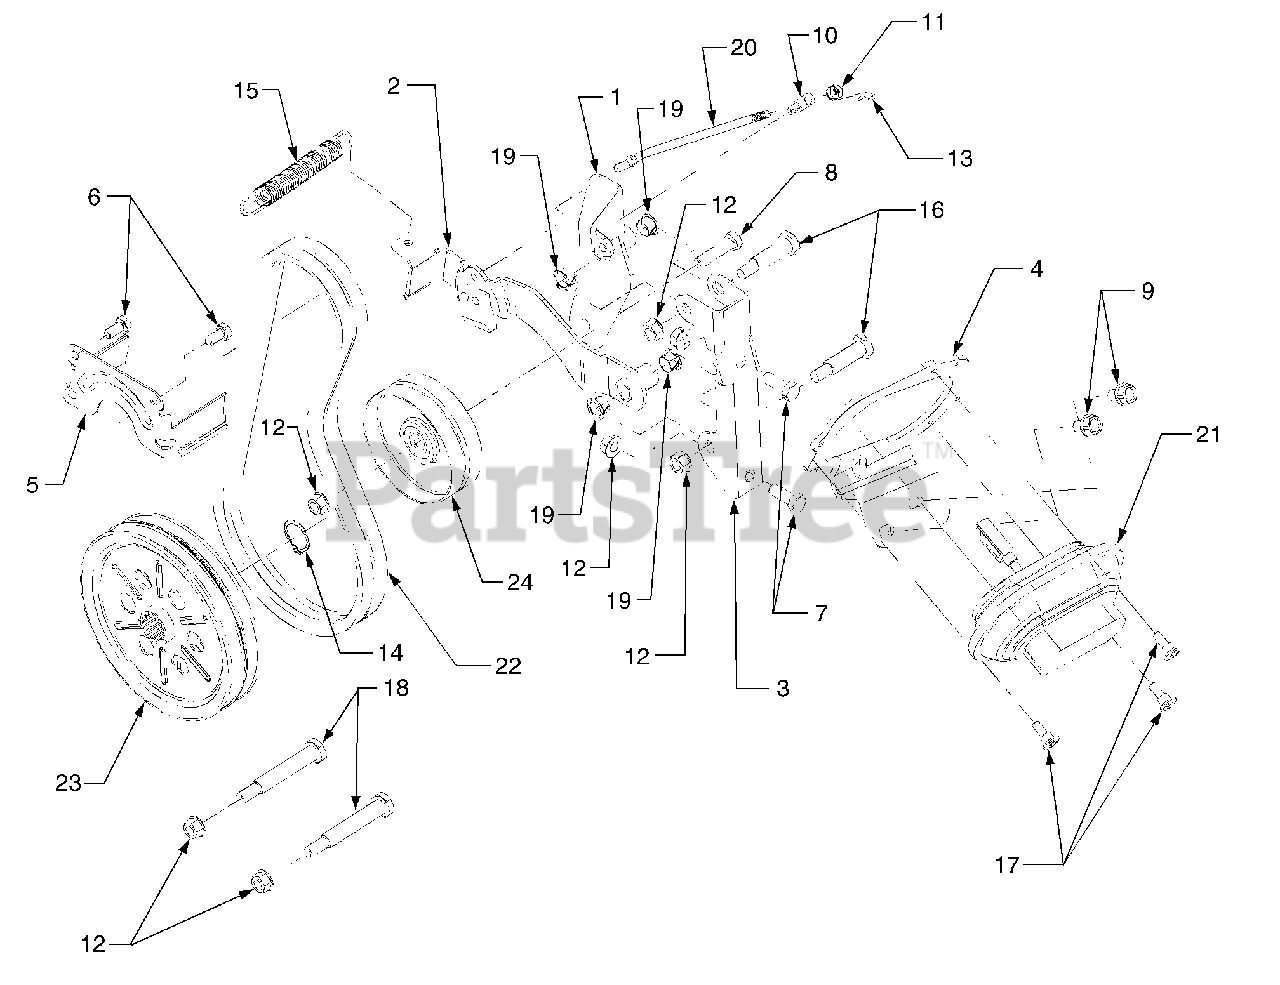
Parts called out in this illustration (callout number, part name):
1	Bracket, Idler
2	Bracket Assembly, Brake
3	Bracket, PTO Mounting
4	Bracket, Actuator
6	Screw, Hex Cap 5/16-24 x .625 GR5
7	Screw, Hex Cap 3/8-16 x 1.0 GR5
8	Screw, Hex Cap 3/8-16 x 1.5 GR5
9	Screw, Hex Wash. Hd. Tapp 3/8-16 x .75
10	Ferrule, Brake Adjustment
11	Nut, Hex Insert Lock, 1/4-20
12	Nut, Flange Lock, 3/8-16
13	Pin, Internal Cotter
14	Snap Ring, 1.0 Dia Shaft
15	Spring, Extension, .530 x 4.74
16	Shoulder Screw, .498 x 1.45
17	Shoulder Screw, .375 x .28
18	Shoulder Screw
19	Bearing, Nylon Flange
20	Rod, PTO Brake
21	Vacuum Actuator
22	V-Belt, A-Section x 37.63
23	Pulley, PTO Drive. 6.75-Double
24	Pulley, Flat Idler, 4.0
